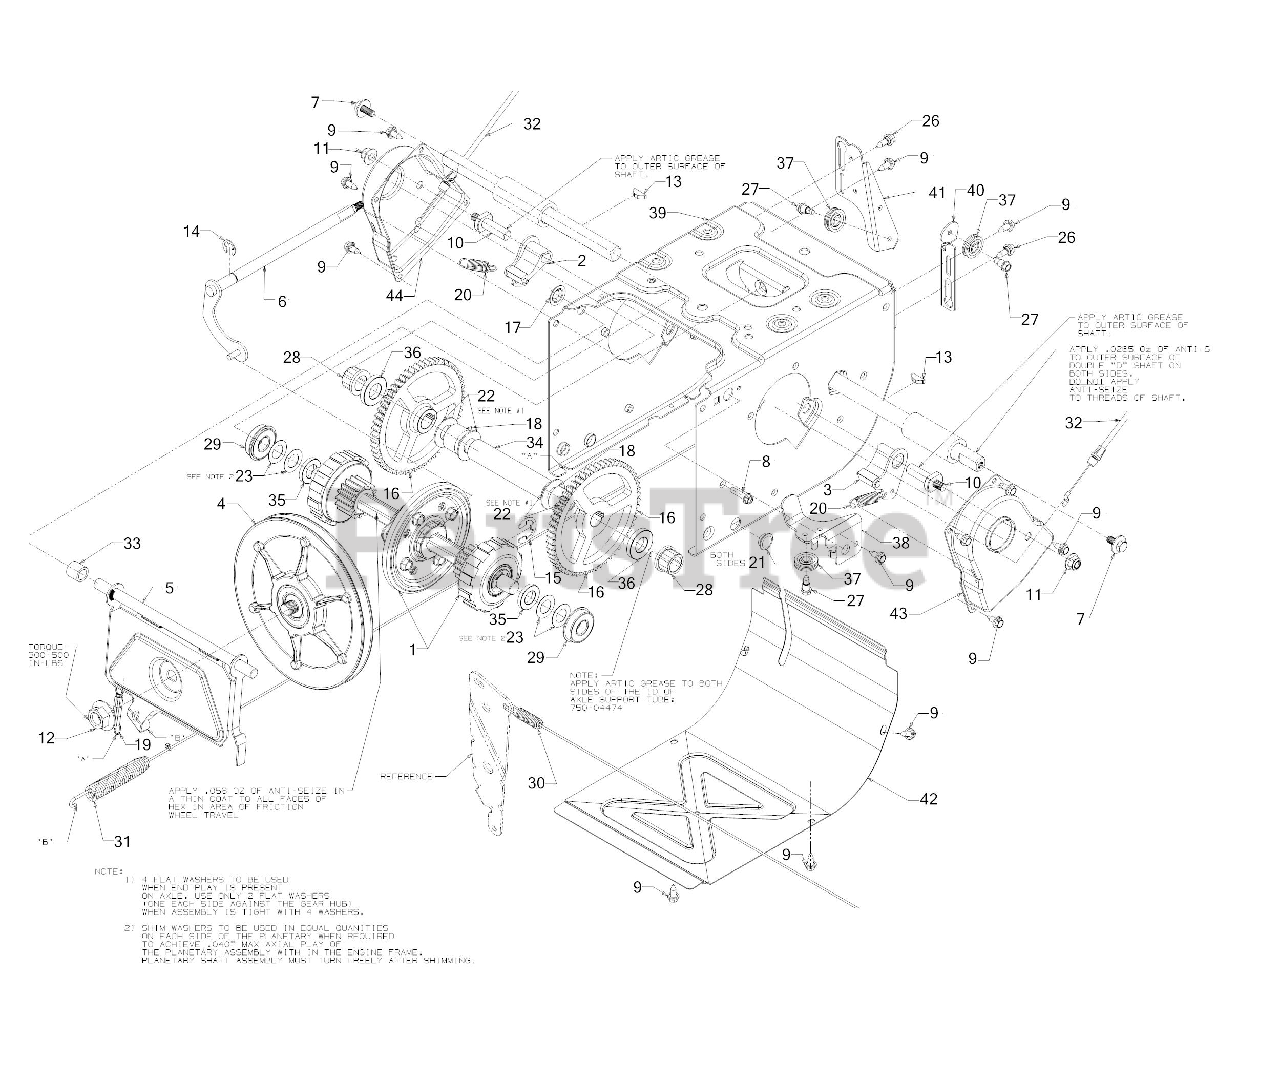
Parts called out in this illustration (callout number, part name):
1	PLANETARY SHIFT ASSEMBLY
2	DOGG ASSEMBLY (RH)
3	DOGG ASSEMBLY (LH)
4	FRICTION WHEEL DISC ASSEMBLY
5	FRICTION WHEEL BRACKET
6	SHIFT ROD ASSEMBLY
7	SCREW 5/16-24 x .750 GR5
8	SCREW 1/4-20 x 1.00
9	SCREW 1/4-20X.625
10	ACTUATOR SHAFT
12	FLANGE NUT 5/8-18
13	KEY 3/16 x 3/4
14	E-RING FOR .500
15	RETAINING RING
18	SPACER: .76ID x .75
19	EXTENSION SPRING
20	EXTENSION SPRING
22	FLAT WASHER .760ID X1.49OD x .06
23	FLAT WASHER .67X 1.174X .02
24	GREASE (NOT SERVICEABLE)
25	ARCTIC GREASE (NOT SERVICEABLE)
26	SHOULDER SCREW
27	SHOULDER SCREW
28	FLANGE BEARING
29	BALL BEARING
30	AUGER DRIVE CABLE 47.48"
31	WHEEL DRIVE CABLE 44.955"
32	STEERING CABLE
33	SPACER-.513 ID x .703 OD x .69
34	AXLE SUPPORT TUBE
36	AXLE SPACER
37	CABLE GUIDE ROLLER
38	AUGER CABLE BRACKET
40	AUGER CABLE GUIDE BRACKET
41	GUIDE BRACKET
43	STEERABLE DRIVE SHAFT RETAINER (LH)
44	STEERABLE DRIVE SHAFT RETAINER (RH)
